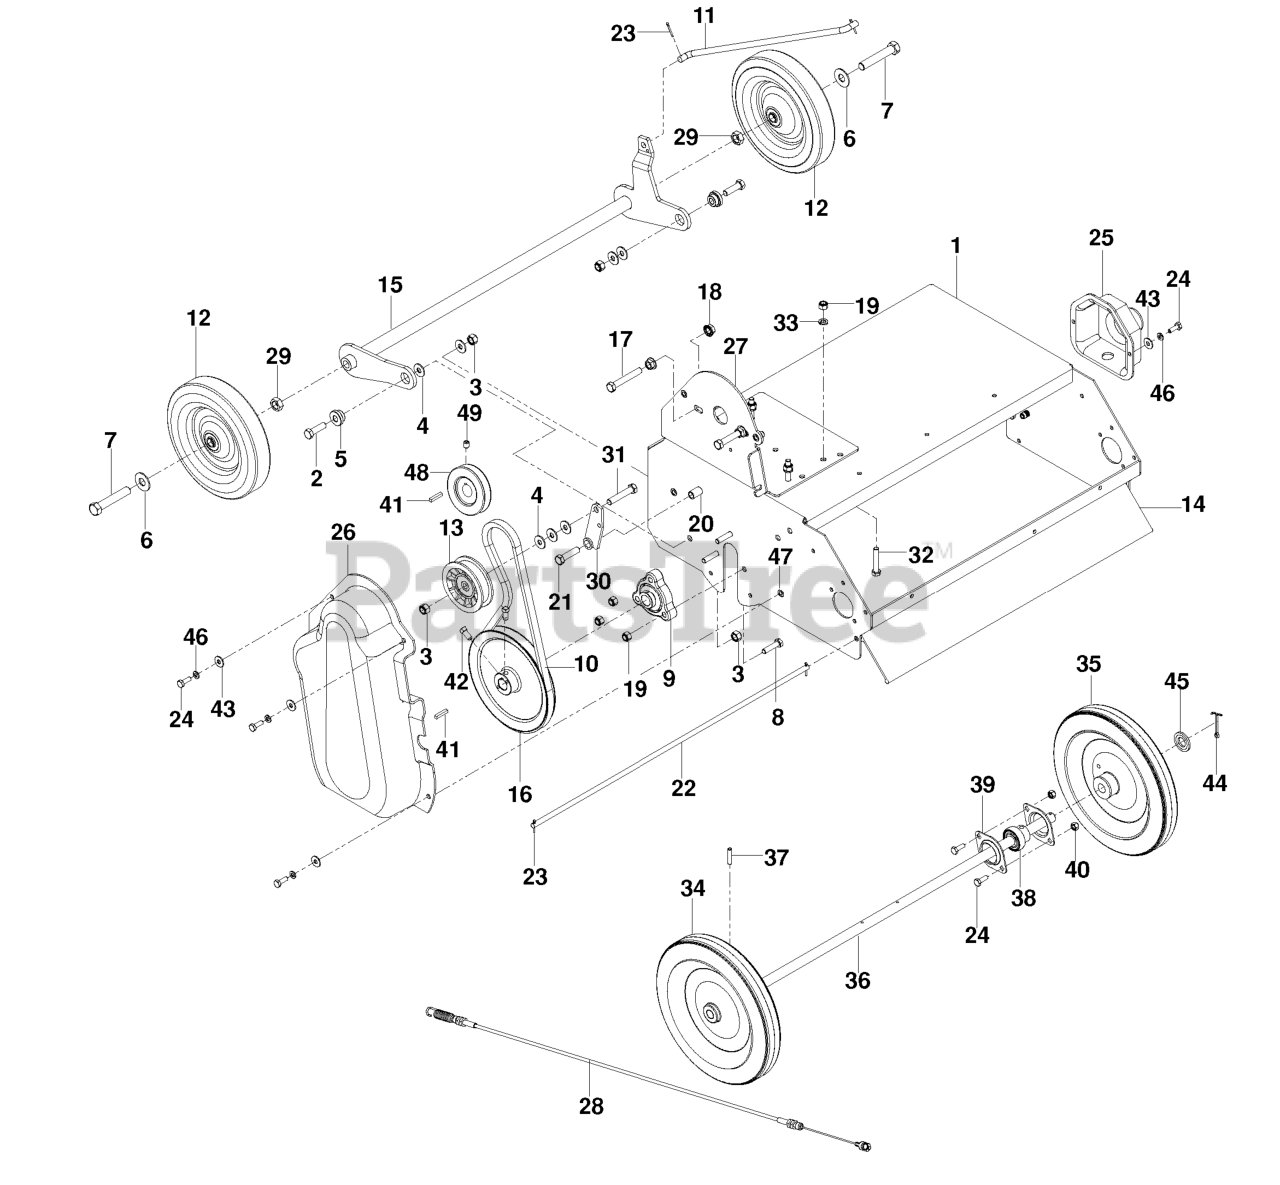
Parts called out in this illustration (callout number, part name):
1	WLDMT, BODY - ORANGE DT22
2	HCS 3/8C X 1 1/4 GR5
3	NUT 3/8-16 NYLOC
4	WASHER 5/16 FLAT
5	BUSHING RAKE
6	WASHER 1/2 FLAT
7	HCS 1/2C X 2 3/4
8	HCS 5/16C X 1 1/4
9	BEARING, FLANGED
10	BELT, DRIVE RAKE/SLICER DFS
12	WHEEL 8 X 1 3/4 RAKE
13	PULLEY, IDLER RAKE & ZTR
15	FRONT AXLE
16	PULLEY, MAIN SHAFT
17	HCS 3/8C X 2 1/2
18	NUT 3/8C WHIZ
19	NUT 5/16 NYLOC
20	BEARING, ONLITE RAKE/DT
21	HCS 3/8C X 1 1/2
23	COTTER PIN 3/32 X 3/4
24	HCS 1/4C X 3/4 HCS
25	SHAFT GUARD
26	BELT GUARD
27	BACKING PLATE ORANGE
28	CABLE POWER RAKE
29	NUT 1/2 HEX JAM
30	IDLER ARM - ORANGE
31	HCS 3/8C X 2
32	HCS 5/16C X 1 3/4
33	WASHER.LOCK.HVY.HLCL.SPR.5/16
34	WHEEL 10 X 1 3/4
35	WHEEL 10 X 1 3/4
36	AXLE, REAR
37	PIN ROLL 1/4 X 1-1/8
38	DNB BRACKET C/S LIFT 3/16
39	DNB BRKT UPPER LATCH NONPLATED
40	NUT.1/4-20.HEX.NYLOC.ZD
41	KEY, 3/16 SQUARE
42	SCREW 5/16C X 5/8 SQ HEAD
43	WASHER 1/4 FLAT
44	COTTER PIN
45	WASHER 5/8 FLAT
46	LOCKWASHER 1/4"
47	KNURLED INSERT
48	ENGINE PULLEY - 5.5 HP
49	SET SCREW 5/16 NYLOC
